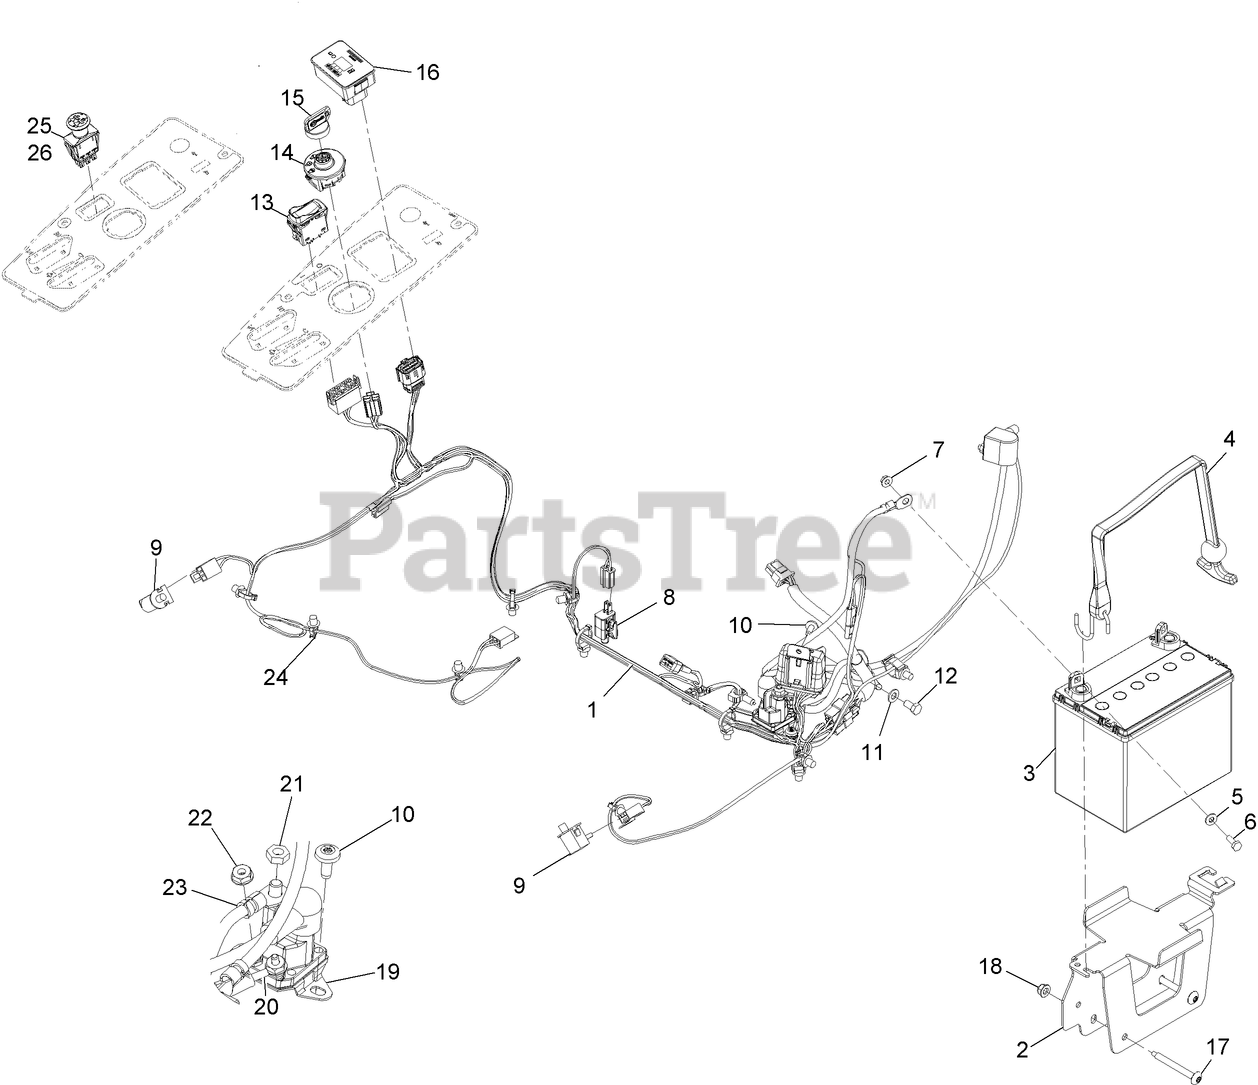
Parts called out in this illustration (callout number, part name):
1	Harness-Main
2	TRAY-BATTERY
3	Battery
4	STRAP, BUNGEE
5	WASHER-FLAT
6	SCREW-HH
9	SWITCH-BAIL
10	SCREW-TORX
11	WASHER-PLAIN
12	SCREW-HH
13	SWITCH-ROCKER, ON-NONE-ON
14	SWITCH-IGNITION
15	KEYS-IGNITION (SPARE PAIR
15	KEY-IGNITION
16	MODULE ASM
17	SCREW-TORX
18	NUT-HF, NI
19	SOLENOID
20	ADAPTER-HARNESS, WIRE
21	NUT-JAM
22	NUT-KEPS
23	CABLE-BATTERY, POSITIVE
24	CLIP-HARNESS
25	SWITCH-PTO
